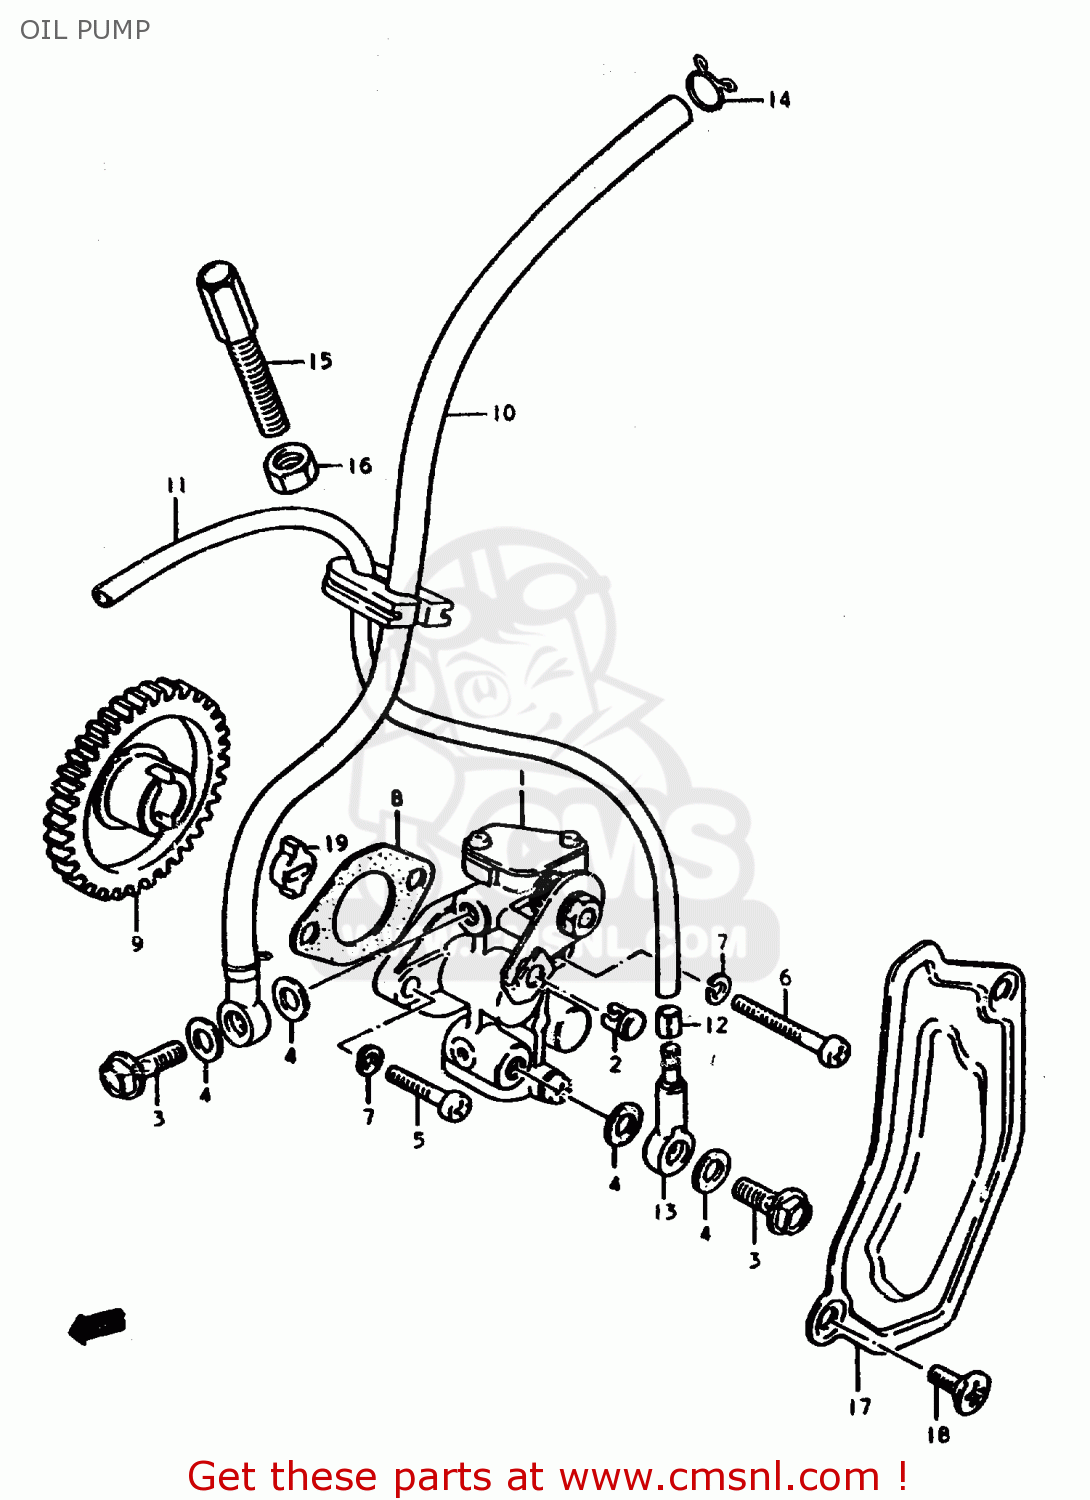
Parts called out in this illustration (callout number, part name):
1	PUMP ASSEMBLY,OIL
2	TERMINAL,CABLE
3	UNION BOLT
4	GASKET(6.2X11X1).2 (NAS)
5	SCREW
6	SCREW
7	LOCK WASHER
8	GASKET,OIL PUMP (NAS)
9	GEAR,OIL PUMP DRIVE
10	HOSE, OIL INLET
11	HOSE,OIL
12	CLIP
13	VALVE,CHECK
14	CLIP
15	BOLT
16	NUT
17	CAP,OIL PUMP INSPECTION
18	SCREW
19	PIECE,OIL PUMP DRIVE
